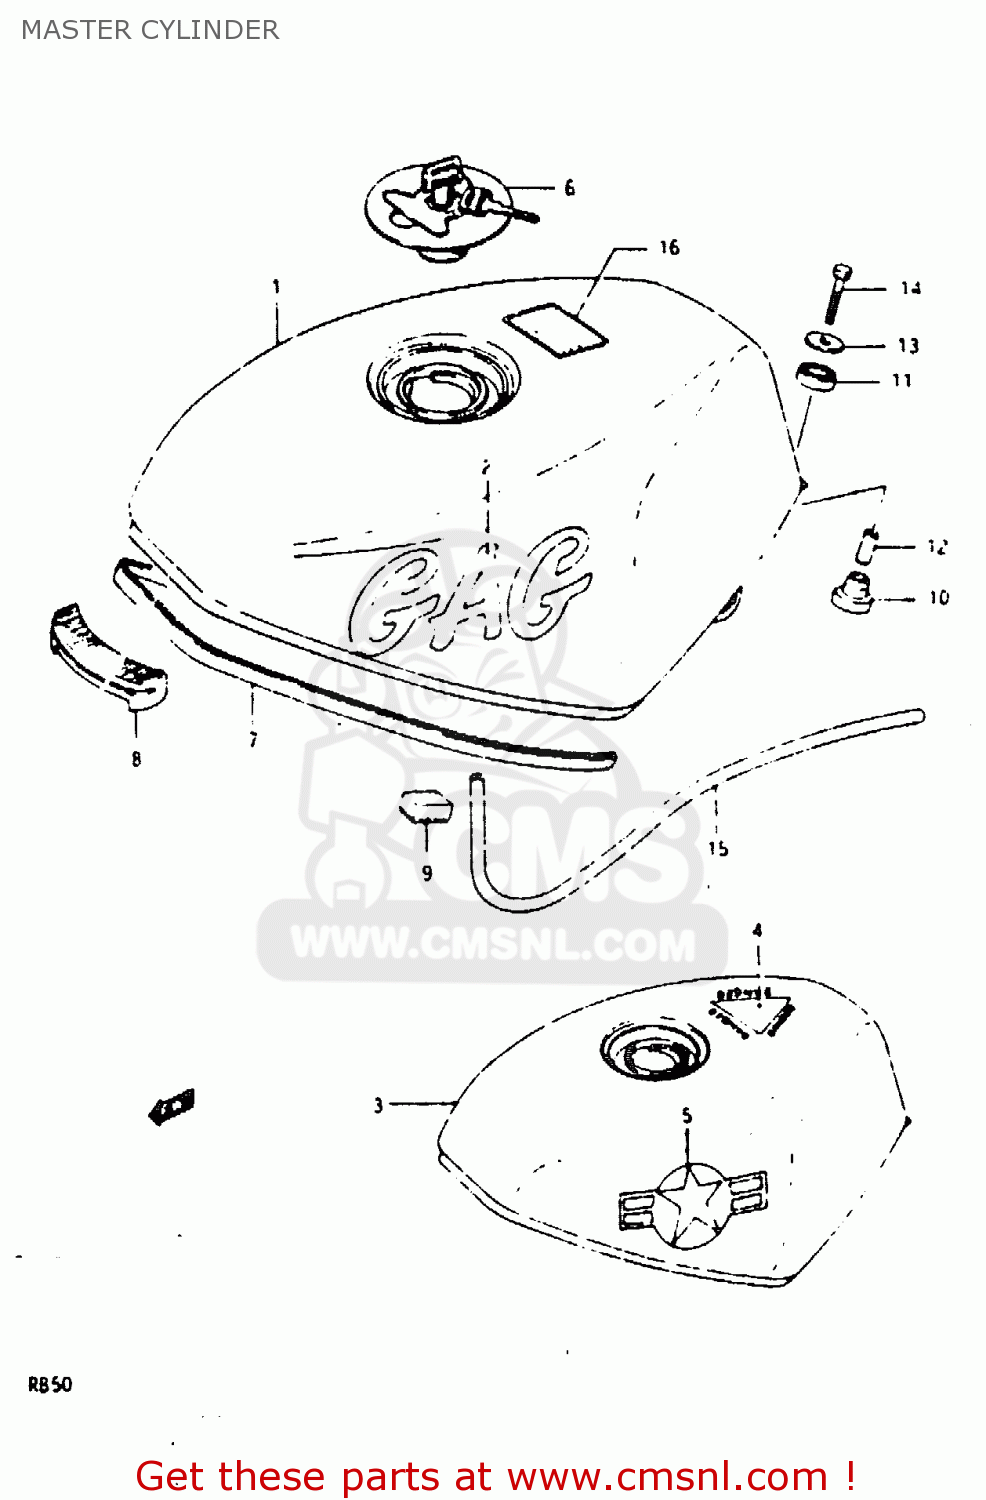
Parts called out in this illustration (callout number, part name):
6	CAP SET,FUEL TANK
7	MOLDING,FUEL TANK
8	CUSHION,FUEL TANK FR
9	CUSHION,FUEL TANK SIDE
10	CUSHION
11	CUSHION
12	SPACER (6.4X9X19)
13	WASHER (6.5X24X1.6)
14	BOLT
15	HOSE,FUEL
16	LABEL
